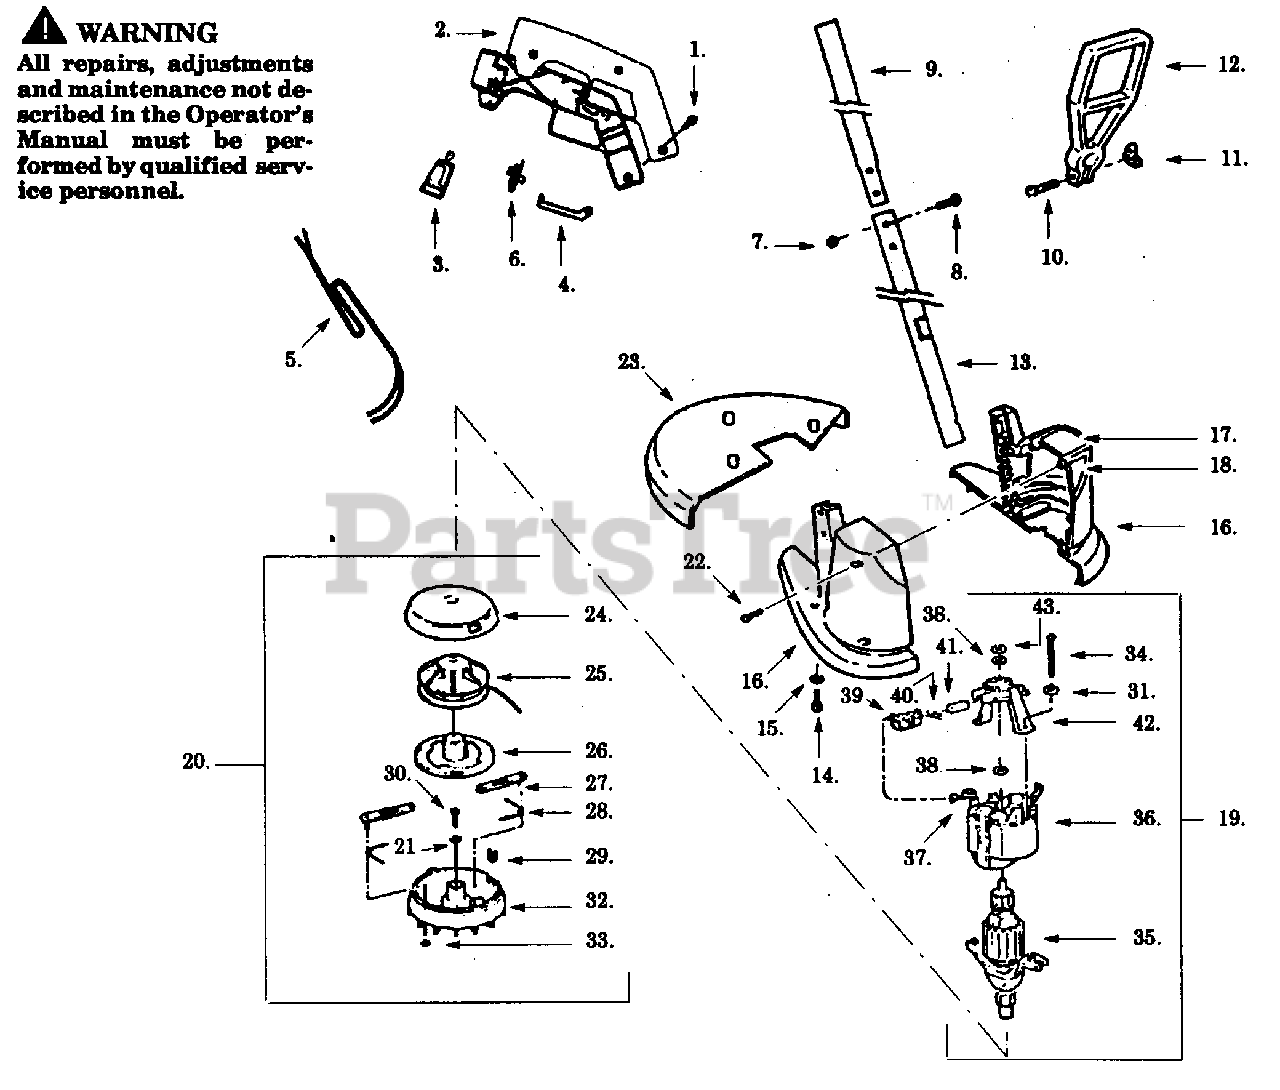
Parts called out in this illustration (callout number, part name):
2	Handle Set
3	Cord Retainer
4	Trigger Switch
5	Harness Assembly
6	On/Off Switch
7	Nut
9	Upper Handle Tube
11	Wing Nut
12	Assist Handle
13	Tube Assy. w/ Decal
16	Housing Set
17	Decal (Not a serviceable part)
18	Decal (Not a serviceable part)
19	Motor Assembly
20	Cutting Head Ass'y
25	Spool w/Line
29	Line Saver
32	Housing Ass'y. (Inc. 27,28,29,32,33)
35	Armature/End Bell
36	Field Ass'y
37	Terminal Bridge
39	Brush Holder Ass'y
42	End Bell Ass'y
43	Retaining Ring
